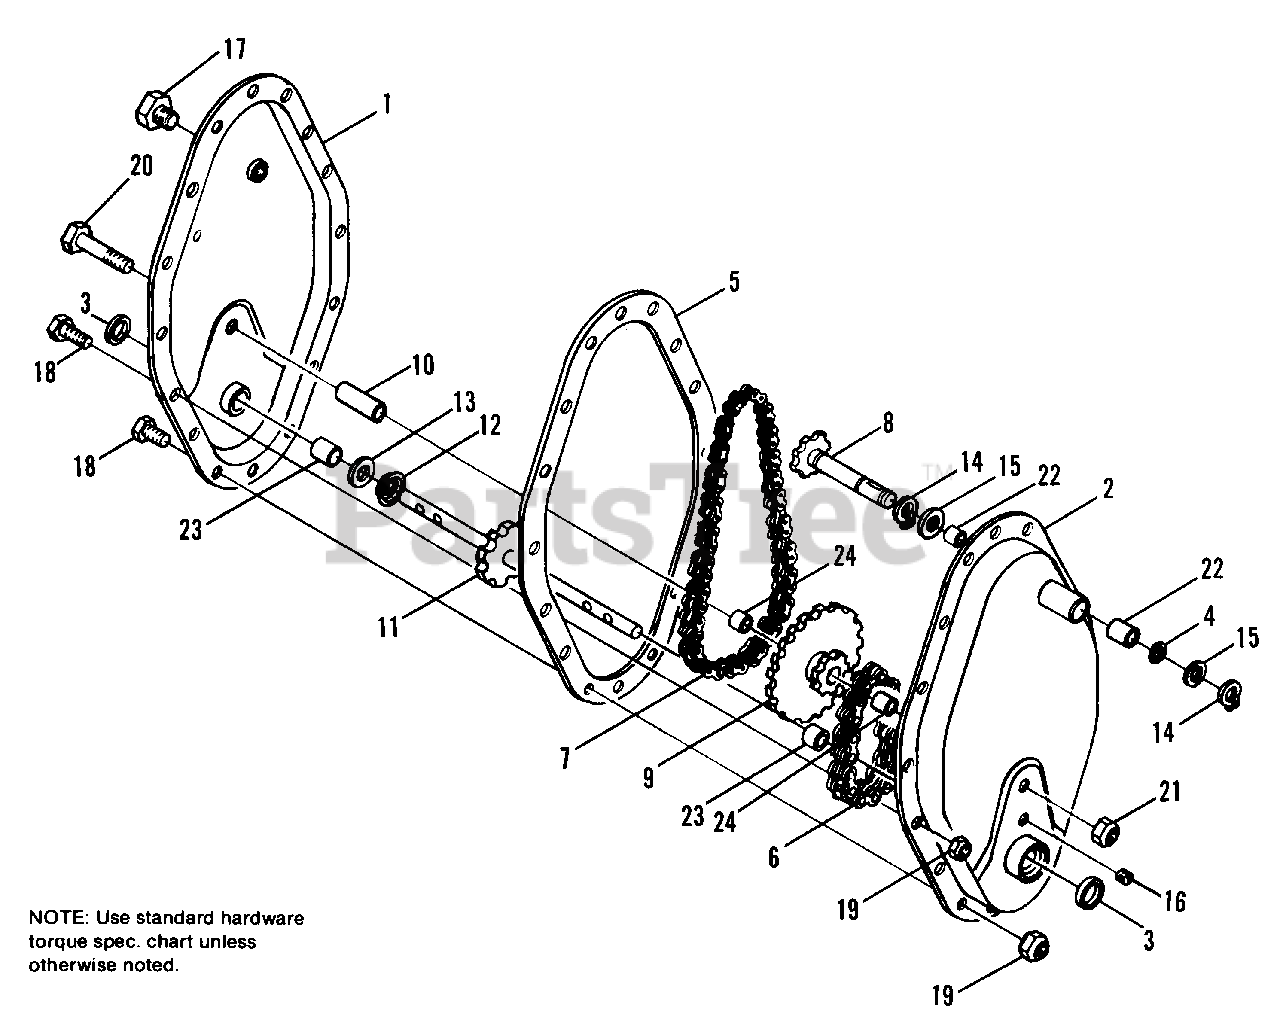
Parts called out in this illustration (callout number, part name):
1	CHAIN CASE ASSEMBLY-R.H. w/Bearings
2	CHAIN CASE ASSEMBLY-L.H. w/Bearings
3	SEAL-Tine Shaft
4	SEAL-Input Shaft
6	CHAIN-Lower
7	CHAIN-Upper
8	INPUT SHAFT ASSEMBLY
9	SPROCKET ASSEMBLY-w/Bearings
10	IDLER SLEEVE
11	TINE SHAFT ASSEMBLY
12	SPACER CUP
13	SHIM-Gear
14	RETAINING RING
15	WASHER-Input Shaft
17	CAP SCREW, Hex Hd. 1/2-20 x 3/4
18	CAP SCREW, Hex Hd. 1/4-20 x 1/2 Heat Treated
19	NUT, Hex Lock 1/4-20 Plated
20	CAP SCREW, Hex Hd. 3/8-16 x 2-1/4" Heat Treated
21	HEX NUT, Cone Lock 3/8-16 Plated
22	BEARING-Input Shaft
23	BEARING-Axle
